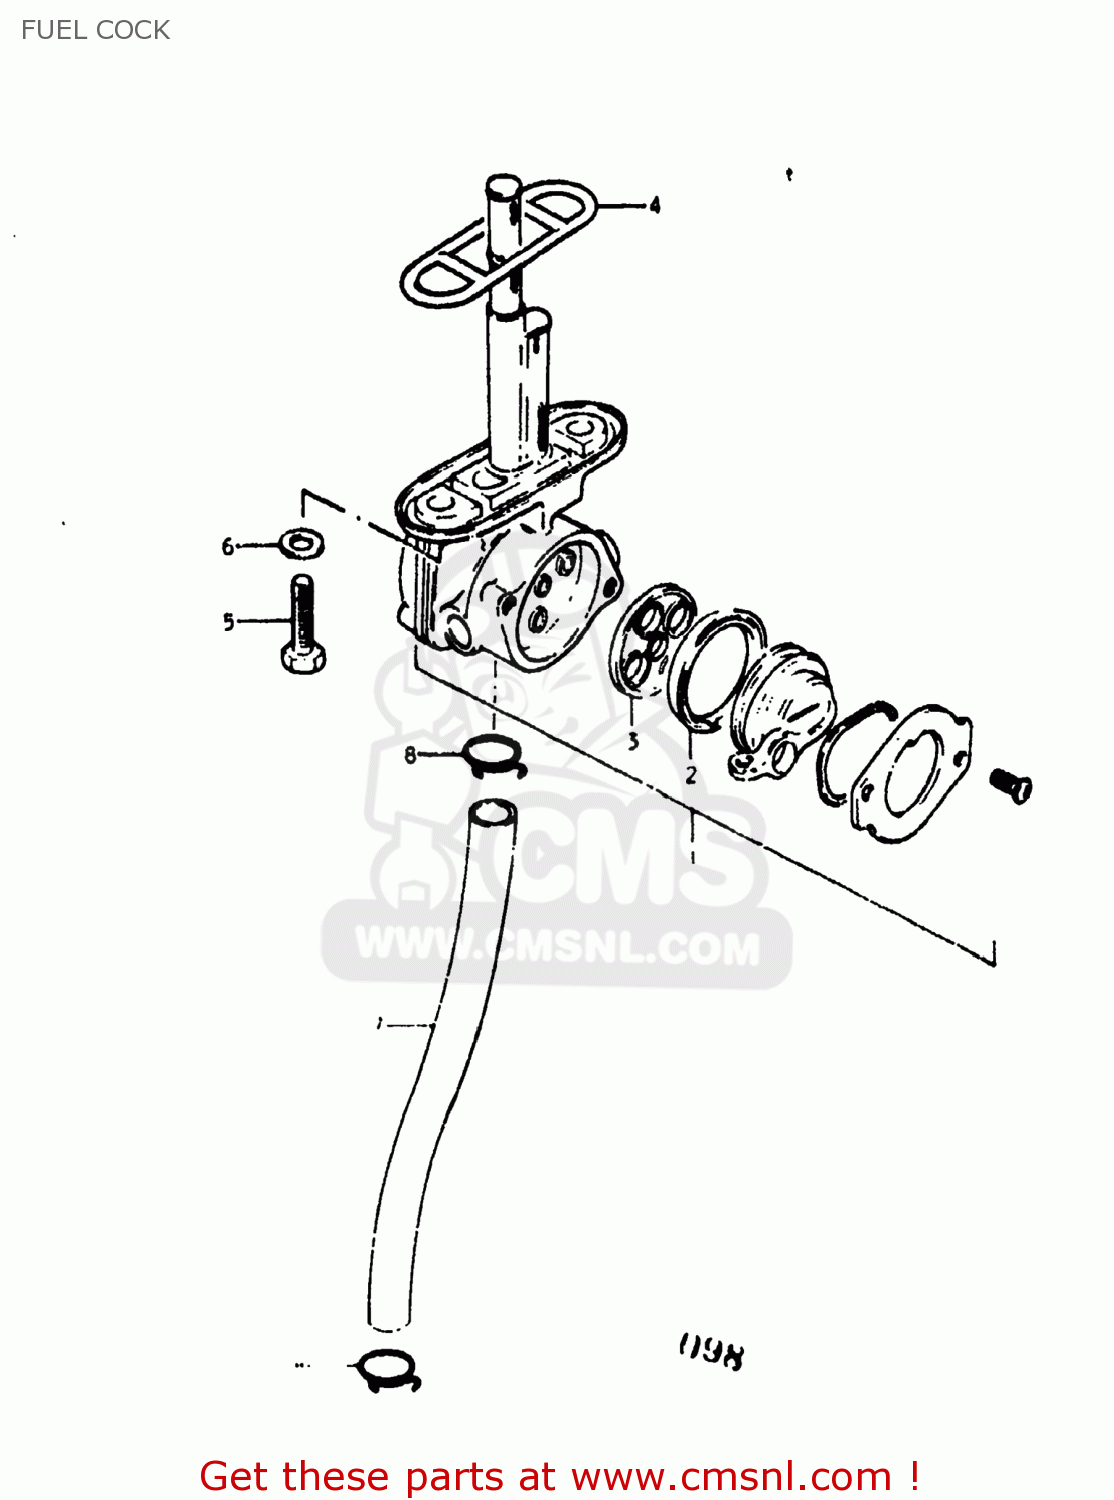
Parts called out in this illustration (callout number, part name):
1	COCK ASSEMBLY,FUEL
2	V SEAL,FUEL COCK
3	GASKET (NAS)
4	GASKET,FUEL COCK (NAS)
5	BOLT(6X20)
6	GASKET
7	HOSE
8	CLIP
